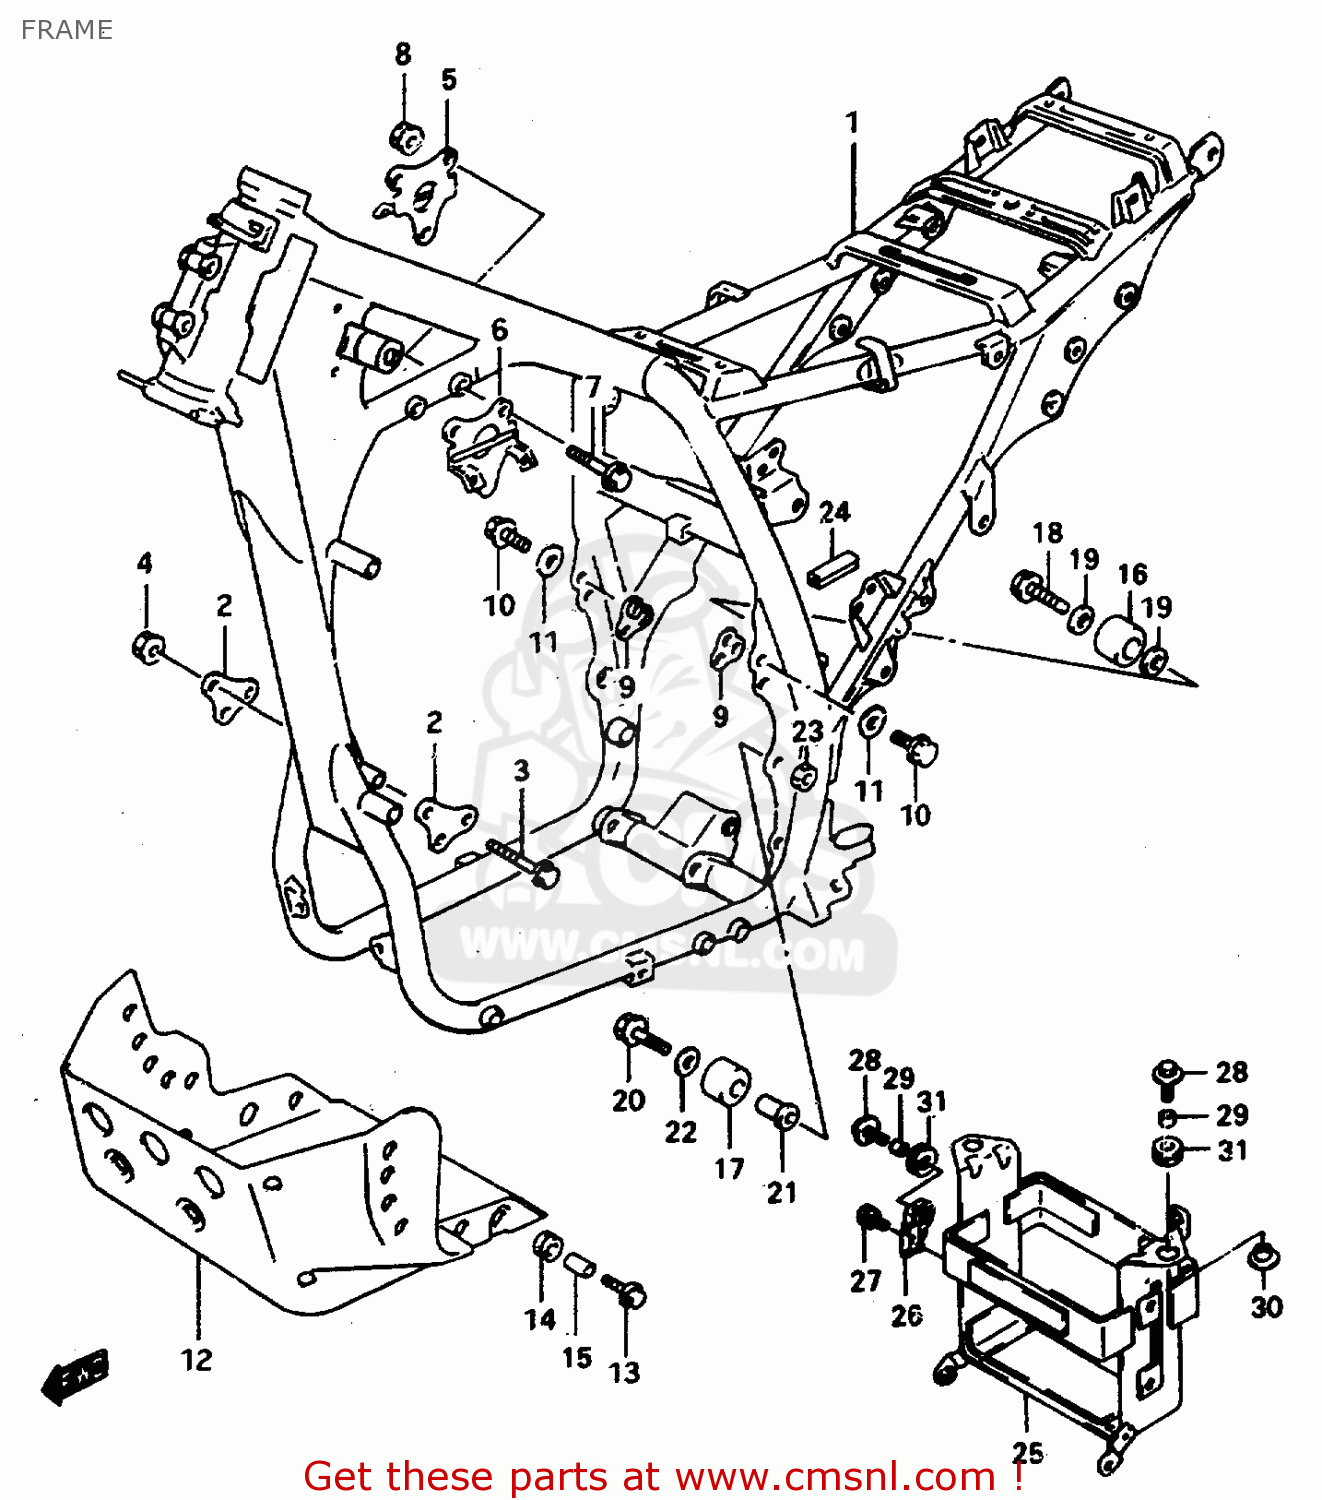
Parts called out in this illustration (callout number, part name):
1	FRAME(CHARCOAL)
2	PLATE,ENG MTG FR
3	BOLT(8X70)
4	NUT
5	PLATE,ENG MTG UPR,R
6	PLATE,ENG MTG UPR,L
7	BOLT(8X53)
8	NUT
9	PLATE, REAR (BLACK)
10	BOLT
11	LOCK WASHER
12	PROTECTOR,ENGINE
13	BOLT(6X20)
14	CUSHION
15	SPACER(6.5X9X9)
16	ROLLER,CHAIN
17	ROLLER,CHAIN CONTROL
18	BOLT(8X41)
19	SHIM(8X12X1)
20	BOLT(10X52)
21	SPACER,CHAIN ROLLER, LWR
22	WASHER
23	NUT 10MM
24	MOLDING
25	HOLDER, BATTERY
26	PLATE, SIDE
27	BOLT
28	BOLT(6X25)
29	SPACER(6.1X9X7.5)
30	WASHER
31	CUSHION
